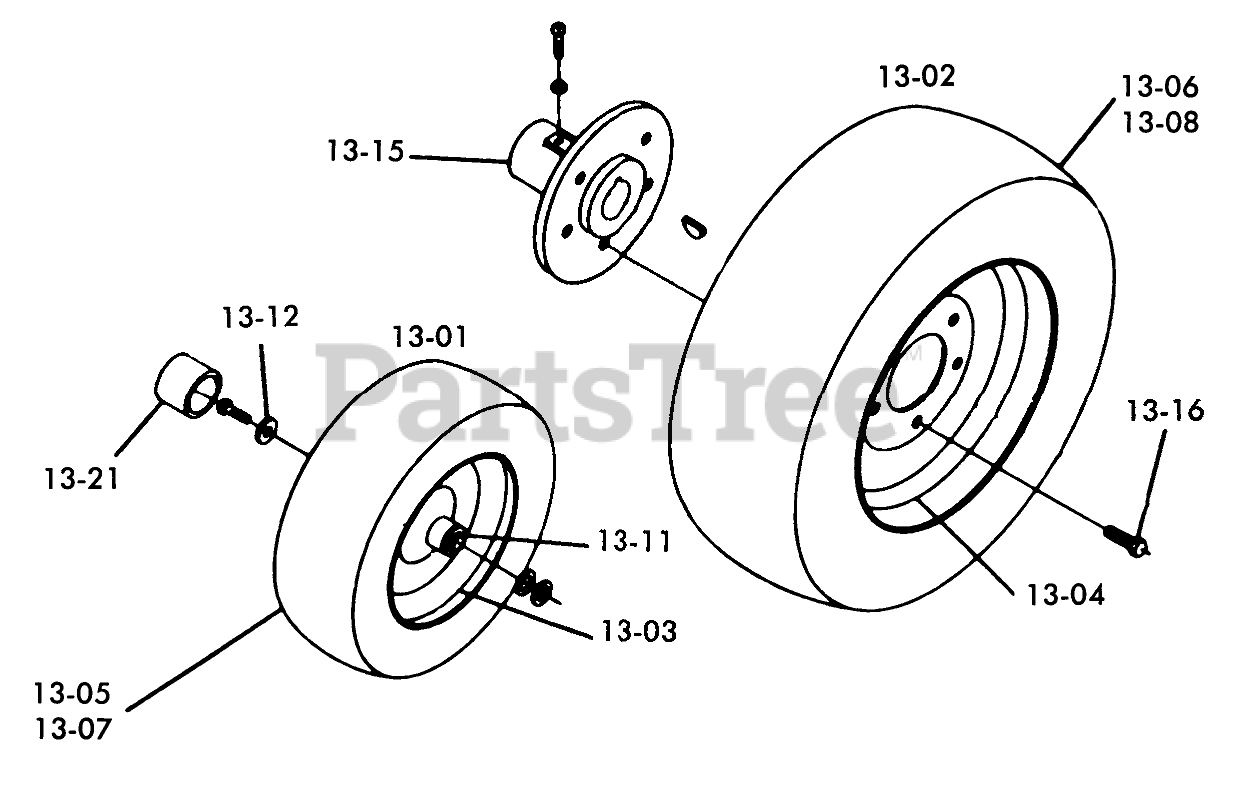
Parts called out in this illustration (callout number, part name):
13-01	Wheel-Complete
13-02	Wheel and Tire
13-04	Wheel
13-04	WHEEL
13-04	VALVE
13-05	TIRE TURF SAVER 16X6.50-8
13-06	Tire
13-07	Tube
13-08	TUBE-INNER
13-11	Bearing
13-11	Bolt
13-12	WASHER
13-12	WASHER-SHIM
13-15	Hub Wheel
13-15	Screw-Set
13-15	Nut
13-15	WOODRUFF KEY
13-16	Lug Nut
13-21	HUB CAP
